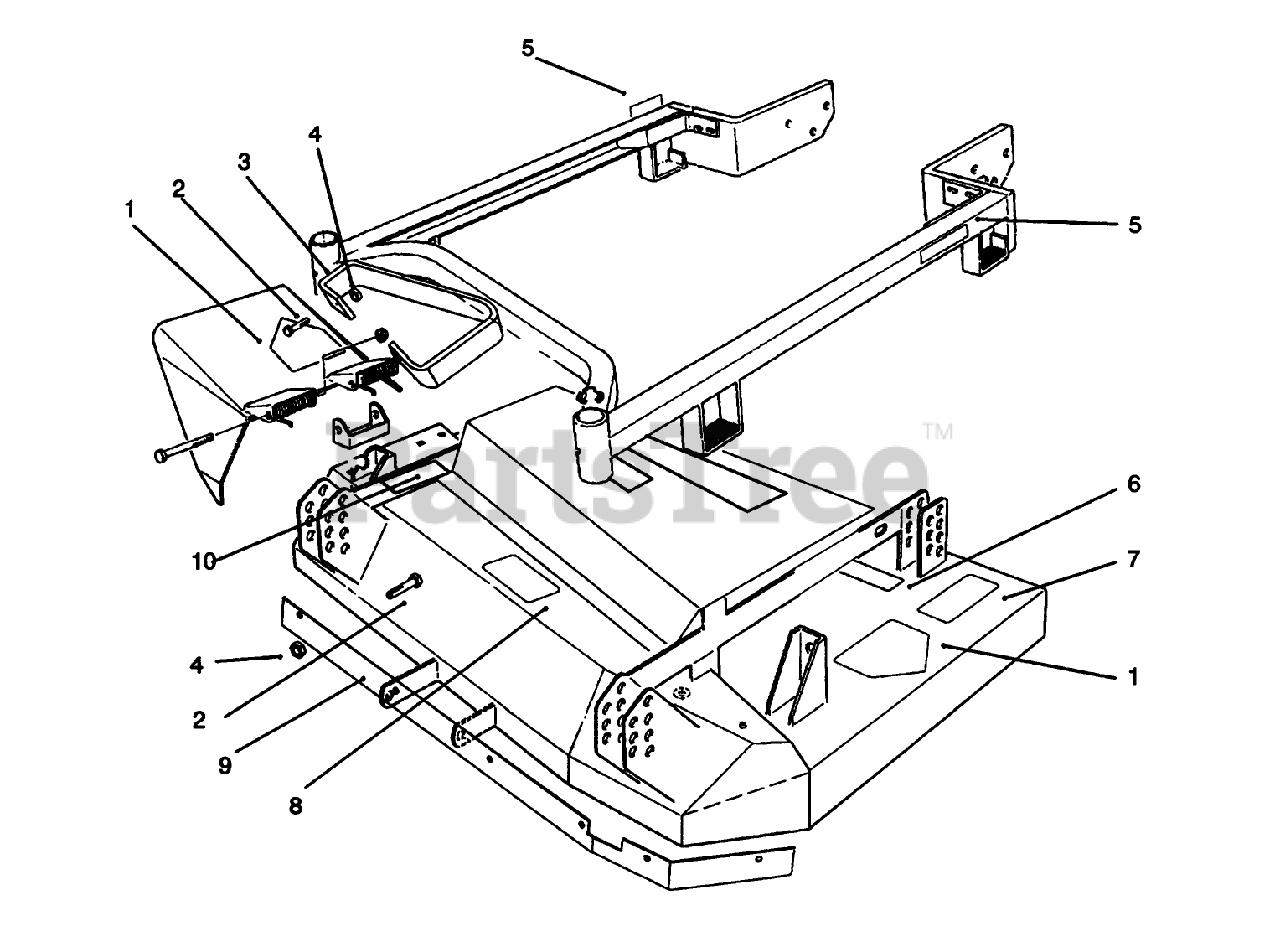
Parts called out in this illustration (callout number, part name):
1	DECAL-DANGER
2	Screw-Hex. Hd.
4	NUT-LOCK, NI
5	DECAL-HOC
7	DECAL-TORQUE, BLADE BOLT
8	DECAL-DANGER
10	DECAL-WARNING
